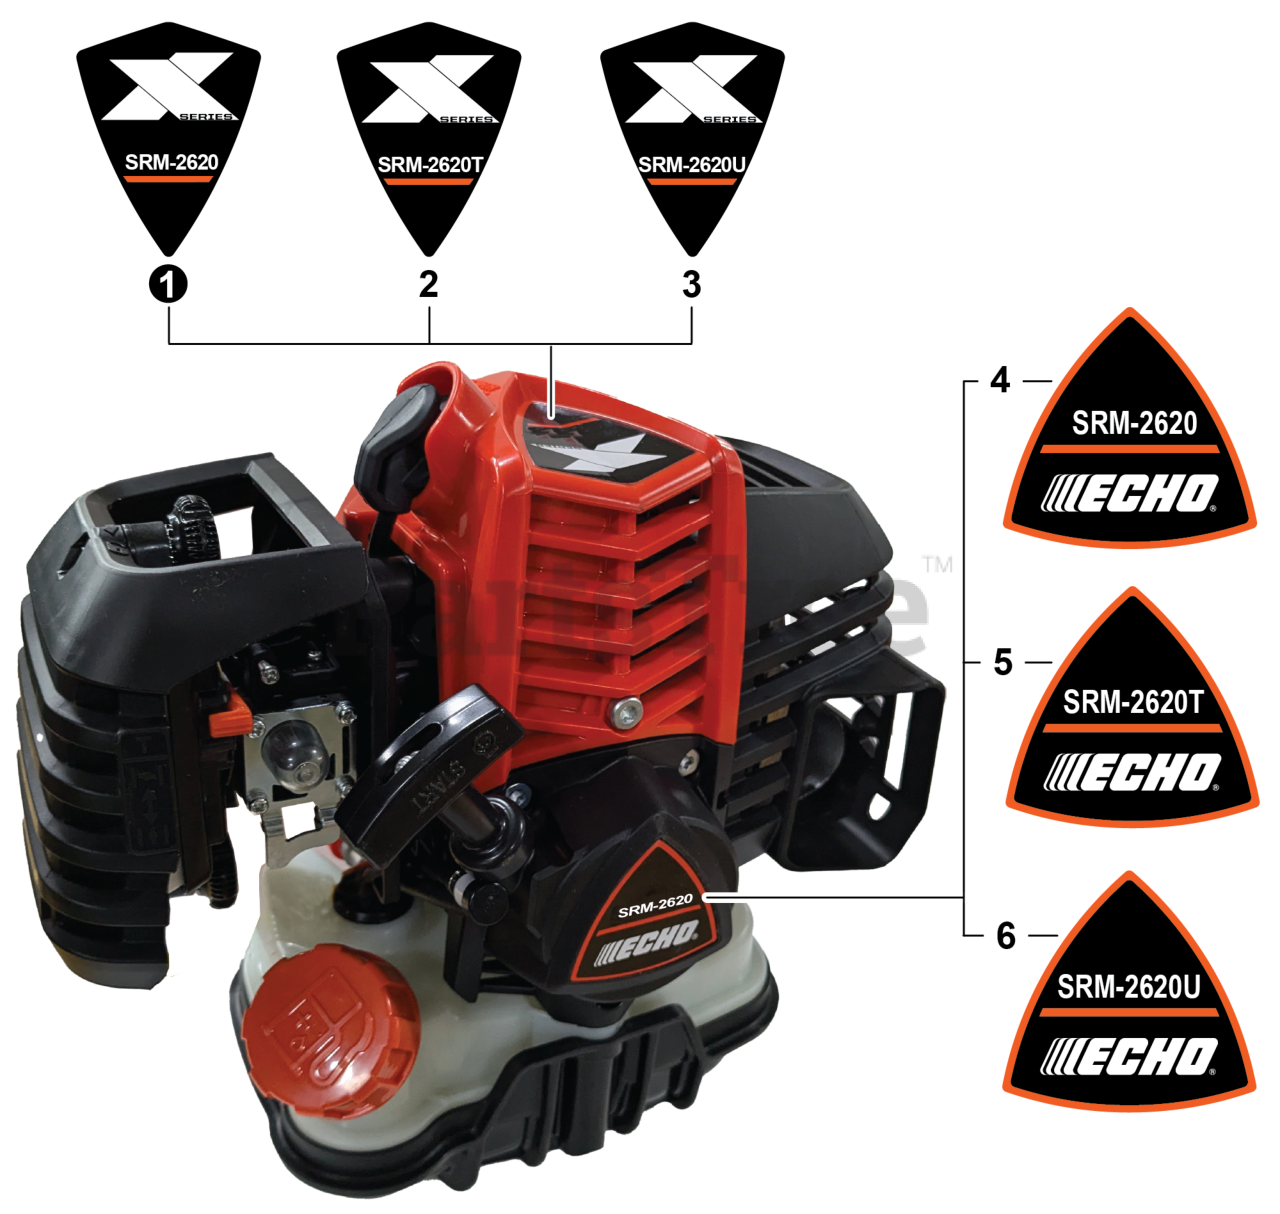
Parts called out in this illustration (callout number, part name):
1	LABEL - MODEL SRM-2620
2	LABEL - MODEL SRM-2620T
3	LABEL - MODEL SRM-2620U
4	LABEL - STARTER - SRM-2620
5	LABEL - STARTER - SRM-2620T
6	LABEL - STARTER - SRM-2620U
